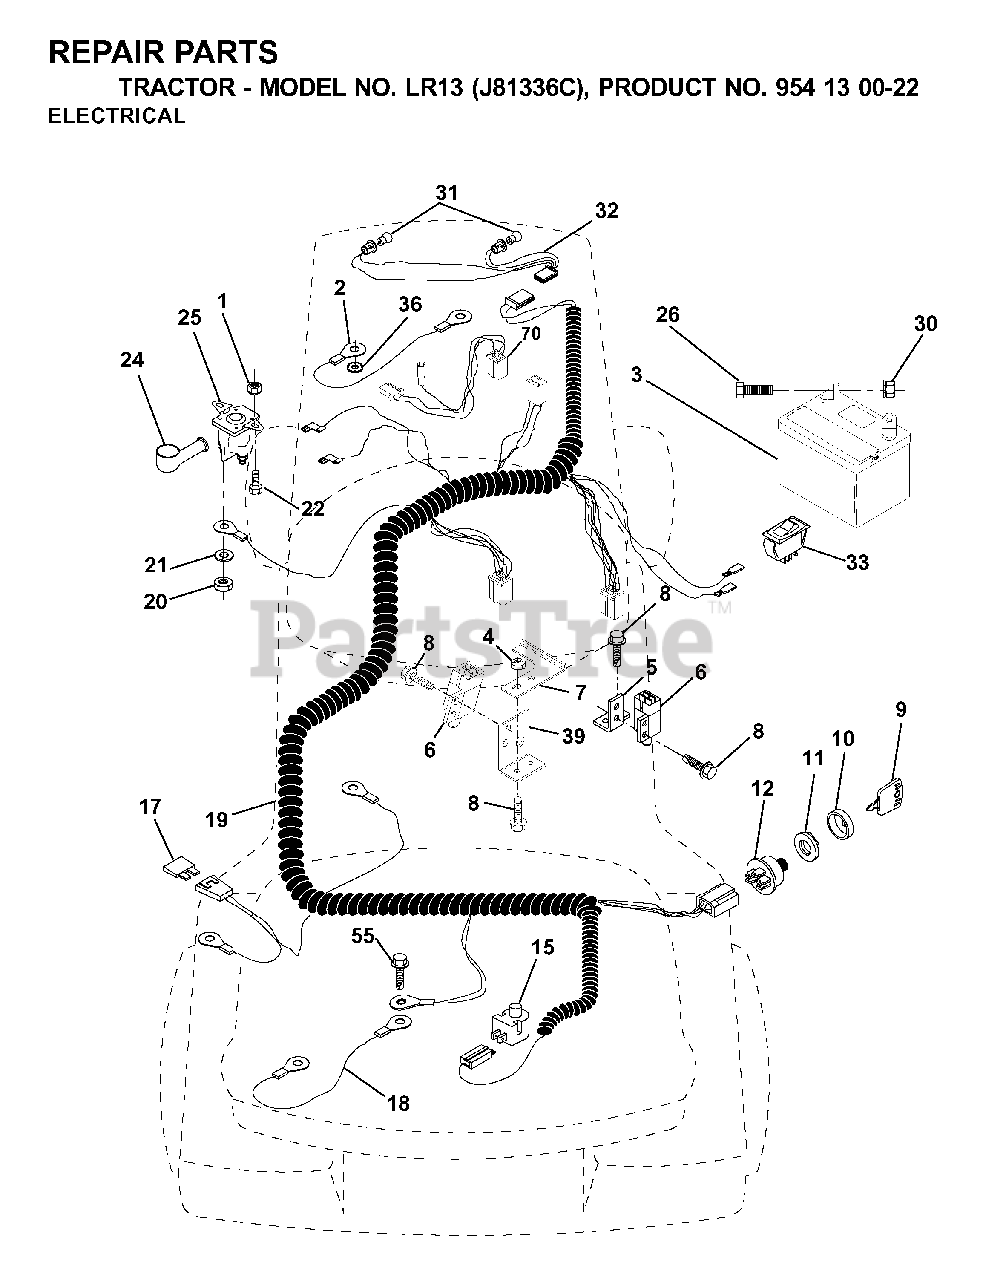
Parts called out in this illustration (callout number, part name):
2	CABLE ASM
5	BRACKET LT
6	SWITCH INTERLOCKT
7	KEEPER, ACTUAT. L.R.
9	KEY MLD GEN DELTA
10	COVER SWITCH KEY
11	NUT, IGNITION
12	IGNITION SWITCH
15	SWITCH SEAT
20	NUT
21	LOCKWASHER
24	TERMINAL COVER
25	SOLINOID
30	NUT
31	LIGHTBULB
33	SWITCH LT
36	LOCKWASHER
